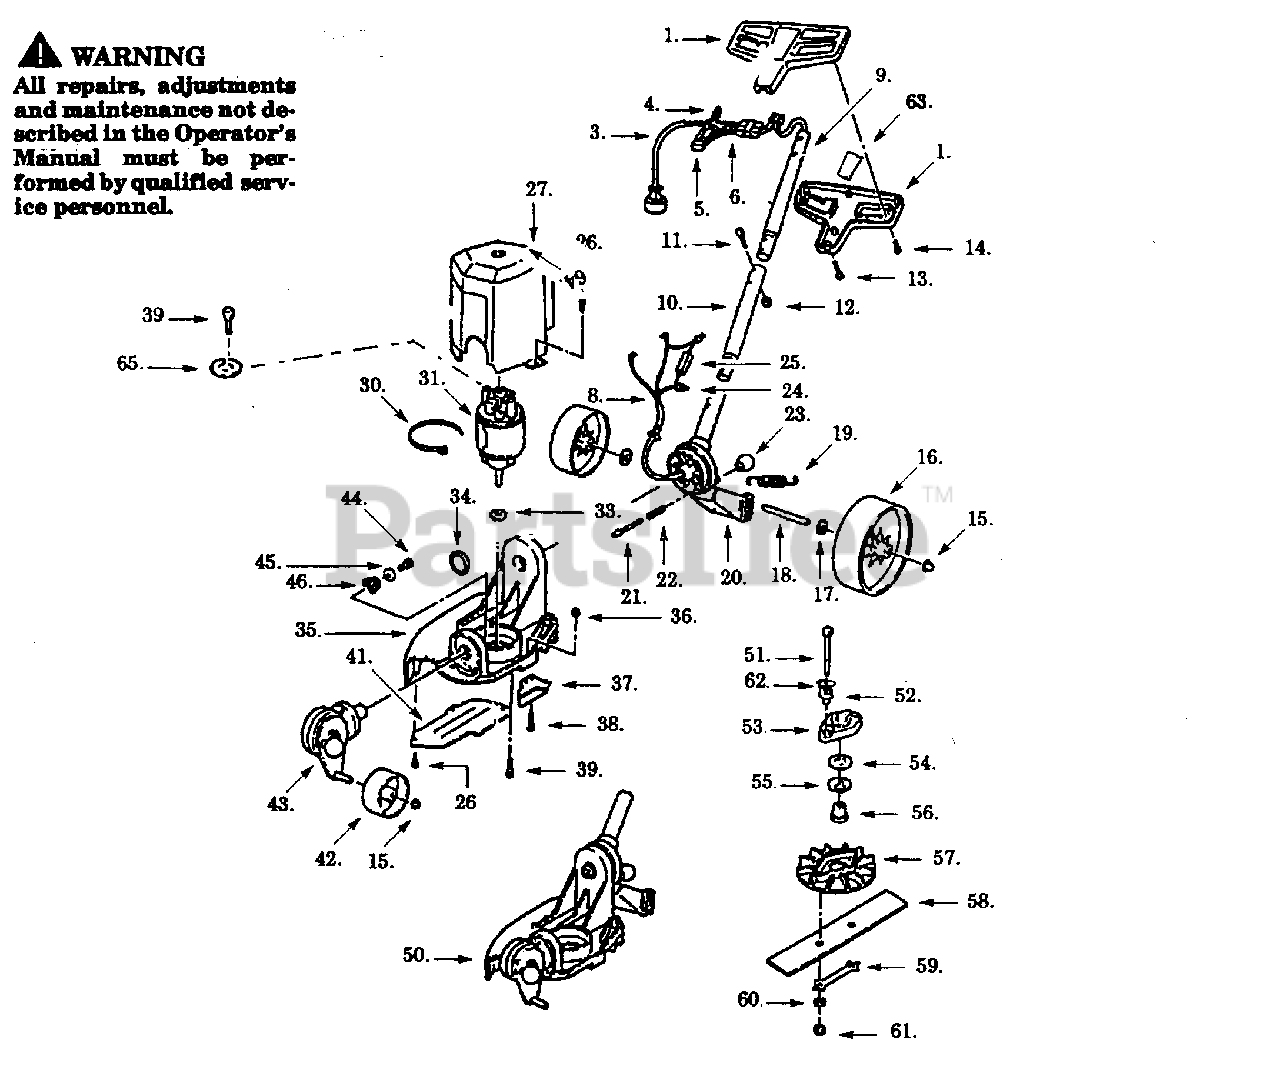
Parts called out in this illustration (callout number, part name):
1	Handle Set
3	Power Cord
4	Wire Nut
6	P.C. Board Ass'y.
8	Harness Ass'y.
9	Upper Tube
10	Lower Tube
15	Push Nut
16	Rear Wheel
18	Rear Axle
20	Rear Swivel
21	Swivel Lock Shaft
22	Swivel Lock Spring
24	Terminal Cap
25	Resister
27	Motor Cover
30	Tie Wrap
31	Motor Ass'y.
34	Retaining Ring
35	Deck Frame
37	Blade Guide
41	Side Guard Plate
42	Front Wheel
43	Front Swivel Ass'y.
46	Front Swivel Spring
50	Edger Frame Ass'y.
52	Insulating Sleeve
53	Clutch Plate
55	Spring Washer
56	Clutch Sleeve
59	Lock Strap
60	Lockwasher
65	Rain Guard
